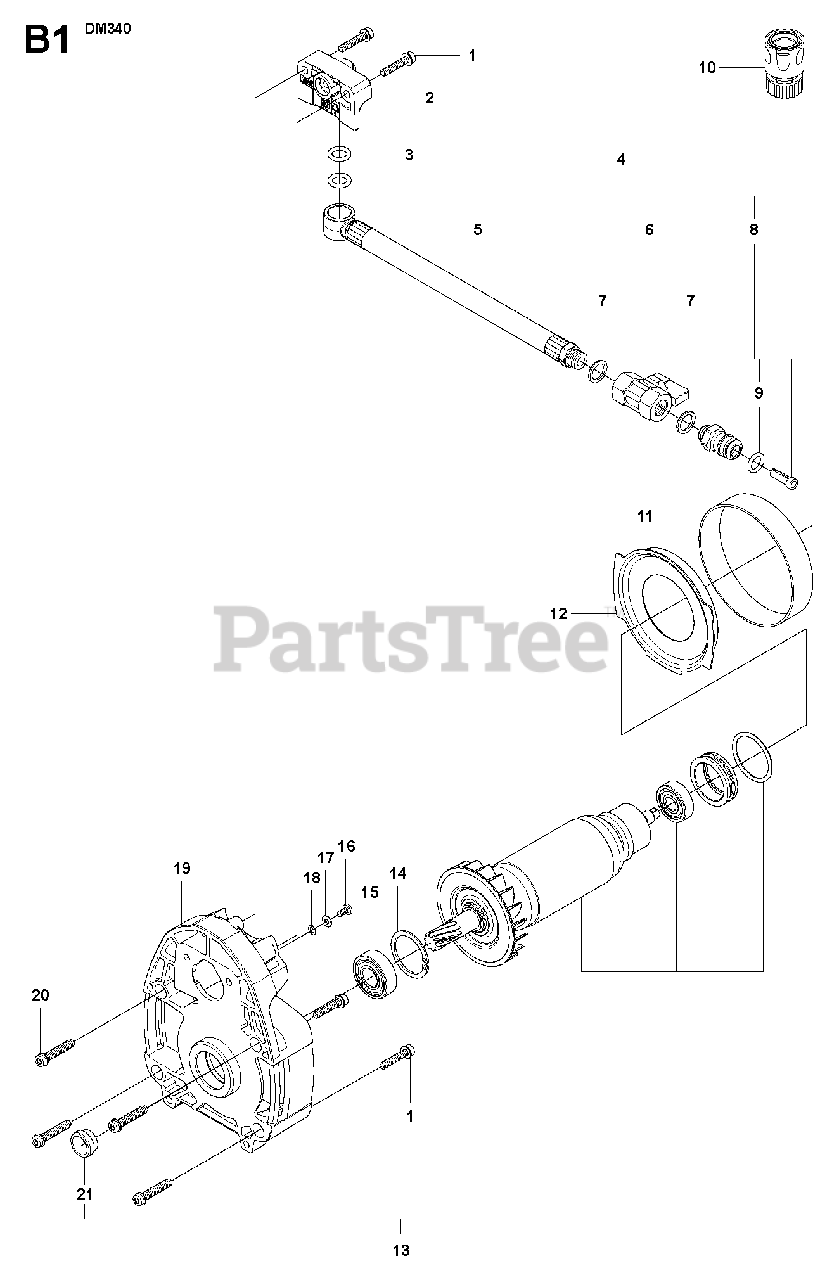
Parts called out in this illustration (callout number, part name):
1	SCREW IHSCFM
4	HOSE ASSYincl 5,6,7,8,9
6	VALVE KITincl 7
8	NIPPLEincl 9
10	COUPLERUSA, CANADA
15	BALL BEARING
16	SCREW CRPANM
